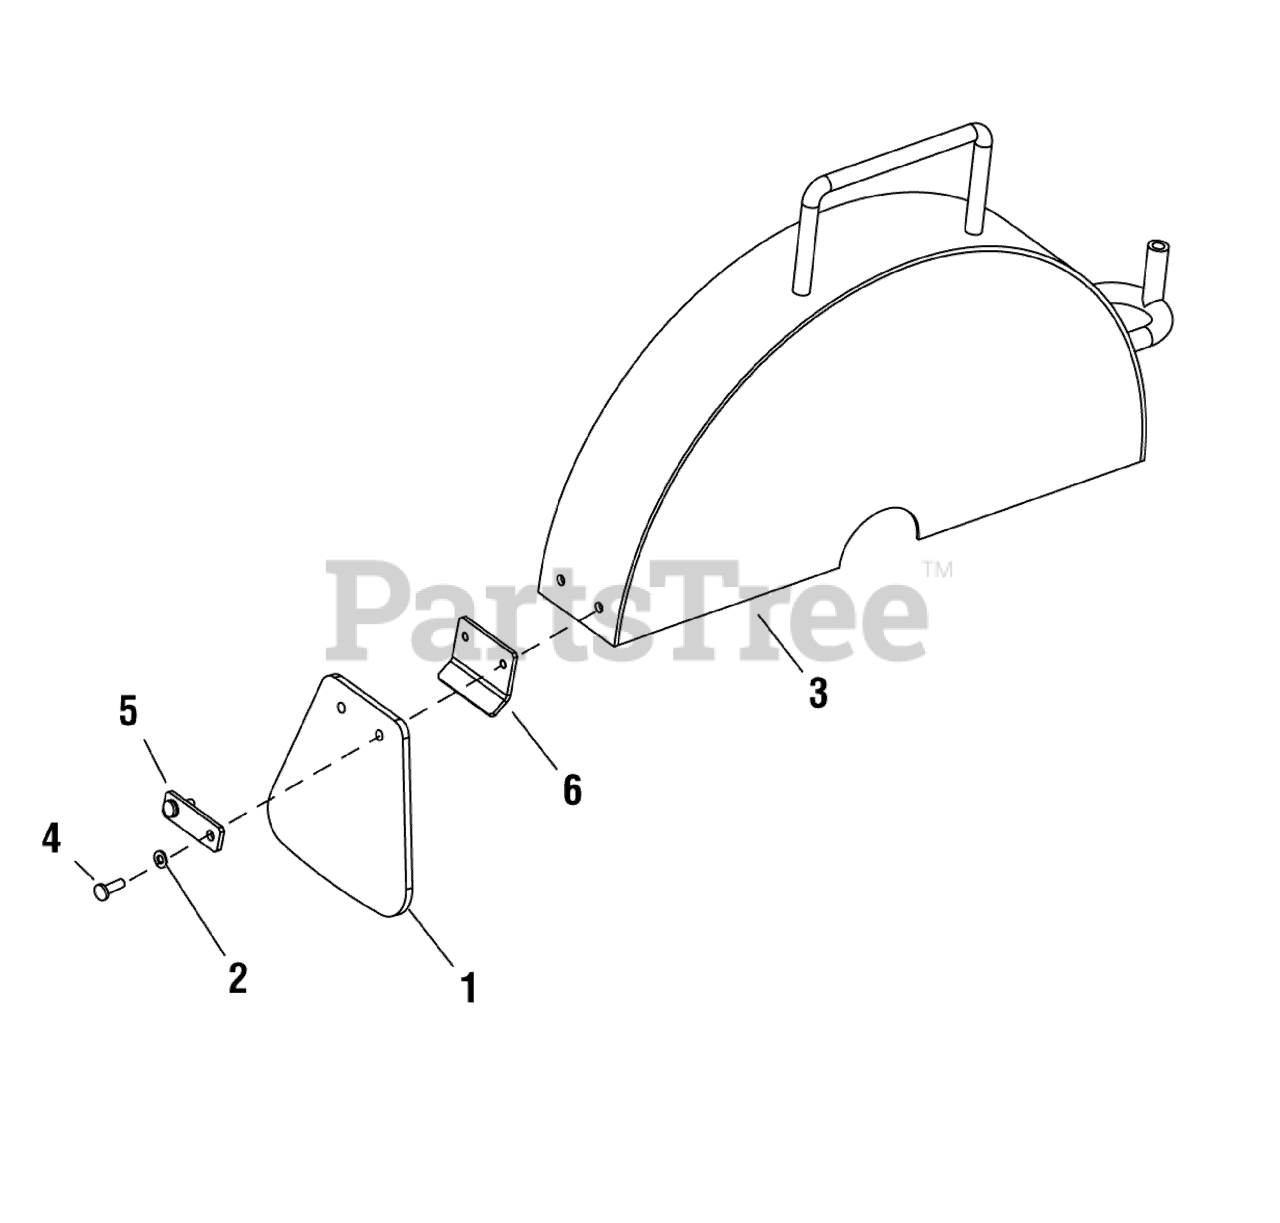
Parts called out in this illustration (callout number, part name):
1	FENDER, Rubber
2	WASHER, Flat, 5
3	BLADE COVER
4	SCREW, Pan Head, Slotted, M5 x 16
5	PLATE, Rubber, Outer
6	PLATE, Rubber, Inner
